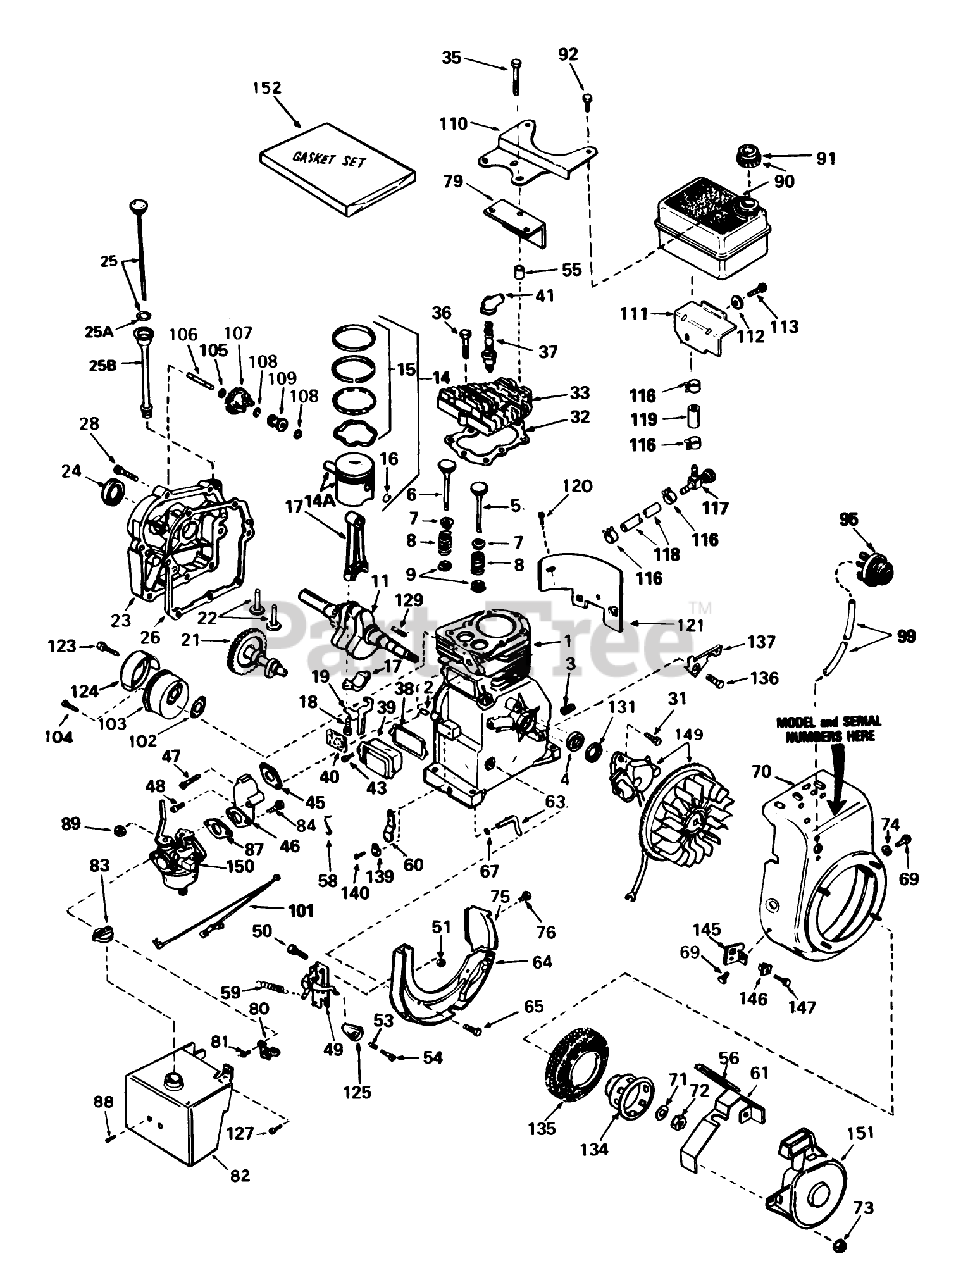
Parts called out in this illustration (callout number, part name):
1	63580 GIL HANDLE BA
2	Pin-Dowel
3	Plug-Drain, Oil (SQH 1/4-18)
4	Seal-Oil
5	Valve, Intake (Std.) (Incl. Ref. #40)
5	Valve, Intake (1/32" oversize)(Incl. No. 40)
6	Valve, Exhaust (Std.)(Incl. No. 40)
6	Valve, Intake (1/32" oversize)(Incl. No. 40)
7	Cap-Upper Valve Spring
8	Spring-Valve
9	Cap-Valve, Spring
11	481-1253 SENATOR RO
14	Piston-Pin Ring Assy. (Std.)(Incl. Ref. #14A, 15 16)
14	Piston-Pin Ring Assy. (.010 oversize)(Incl. Ref. #14A, 15 16)
14	Piston-Pin Ring Assy. (.020 oversize)(Incl. Ref. #14A, 15 16)
14A	Piston Pin Assy. (Std)(Incl. Ref. #16)
14A	Piston Pin Assy. (.010 oversize) (Incl. Ref. #16)
14A	Piston Pin Assy. (.020 oversize) (Incl. Ref. #16)
15	Piston Ring Set Std.
15	Piston Ring Set .010 O.S.
15	Piston Ring Set .020 O.S.
16	Ring-Retaining, Piston Pin
17	Rod Assy., Connecting (Incl. Ref. #17)
18	Bolt-Rod, Connecting
19	53020/22 GIL.HYDRO
21	Camshaft (Compression Release
22	Lifter-Valve
23	Cover, Cylinder (Incl. #24 106)
24	Seal Oil
25	Dipstick
25A	O-Ring
25B	Tube Fill
26	Gasket-Cylinder Cover
28	Screw (1/4-20 x 1-1/4)
31	Screw
32	Gasket-Cylinder Head
33	CYLINDER HEAD
35	Screw (5/16-18 X 2)
36	Screw (5/16-18x1-1/2)
37	Plug, Spark (J17LM or equiv.)
37	Plug, Spark (Champion RCJ-8)
38	Gasket Breather
39	Breather Assembly (Incl. Nos. 52 84)
40	Element-Breather
41	Cover-Spark Plug
43	Screw
45	Gasket-Intake
46	Pipe-Intake (Incl. Ref. #47)
47	Screw-Hex Hd.
48	Screw (1/4-20 x 1-19/32)
49	Control Assembly, Speed (Incl. Ref. #155 thru 158 160)
50	Screw
51	Nut-Lock
53	Spring-Compression
54	Screw
55	pacer
56	Seal, Snowguard
58	Jet-Main
59	Spring-Extension
60	Lever-Governor
61	Guard-Starter
63	Rod-Governor
64	Baffle-Blower Housing
65	Screw (1/4-20x19/32)
67	Washer-Flat
69	Screw
70	Housing-Blower
71	Washer-Belleville
72	Nut-Flywheel
73	Nut and Lock Washer (1/4-28)
74	Washer
75	Baffle-Extension
76	Screw, Hex Washer Hd. Shakeproof Self-drilling
79	Baffle-Heat
80	Bracket-Choke
81	Screw (10-32 x 1/2)
82	Cover, Carburetor
83	Knob-Control
87	Gasket
88	Screw (8-32 X 5/16)
89	Nut and Lock Washer (1/4-28)
90	481-1261 SENATOR TI
91	Cap, Fuel
92	Screw (1/4-15x7/8)
95	Primer Assy.
99	Line, Primer
101	Wire-Ground
102	Gasket Exhaust
103	Muffler
104	Screw
105	Washer-Flat
106	Shaft-Governor
107	Governor Gear ASM
108	Ring-Retaining
109	Spool-Governor
110	Plate-Fuel Tank
111	Bracket-Fuel Tank
112	Washer
113	Screw Assembly
116	Clamp-Line, Fuel
117	Valve-Shut Off
118	Line-Fuel
119	Line-Fuel (8.62)
120	Screw
121	Extension-Blower
123	Screw (1/4-15x7/8)
124	Cover-Muffler
125	Knob-Control
127	Screw (10-32x1/2)
129	Key-Flywheel
131	Gasket Stator
134	Cup-Starter
135	Screen-Starter
136	Screw (10-24 x 9/16)
137	Bracket-Hold Down
139	Clamp-Lever, Governor
140	Screw
145	Bracket
146	Grommet
147	Screw
149	Magneto (The complete magneto in not available as an assembly. The magneto number is shown for reference purposes only. Order component parts individually, as shown in parts list)
150	Carburetor (Incl. #87)
151	Starter Assy., Rewind
152	Gasket Set (Incl. items marked*
